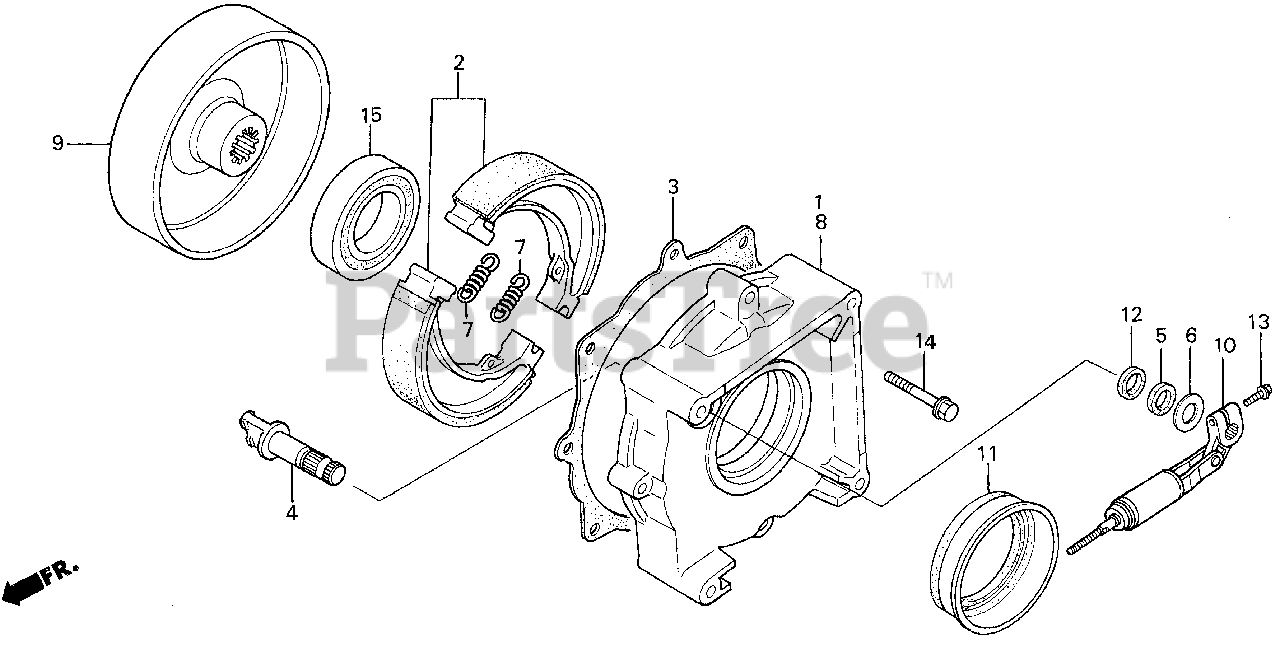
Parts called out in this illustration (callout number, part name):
1	PANEL, R. BRAKE
2	SHOE KIT, BRAKE
3	GASKET, BRAKE PANEL
4	CAM, BRAKE
5	DUST SEAL, BRAKE CAM
6	WASHER, BRAKE CAM
7	SPRING, BRAKE SHOE
8	PANEL, L. BRAKE
9	DRUM, BRAKE
10	ARM, BRAKE
11	DUST SEAL (37X58X9)
12	DUST SEAL (17X23X3) (NOK)
13	BOLT, FLANGE (8X25)
14	BOLT, FLANGE (8X40)
15	BEARING, RADIAL BALL (6007)
